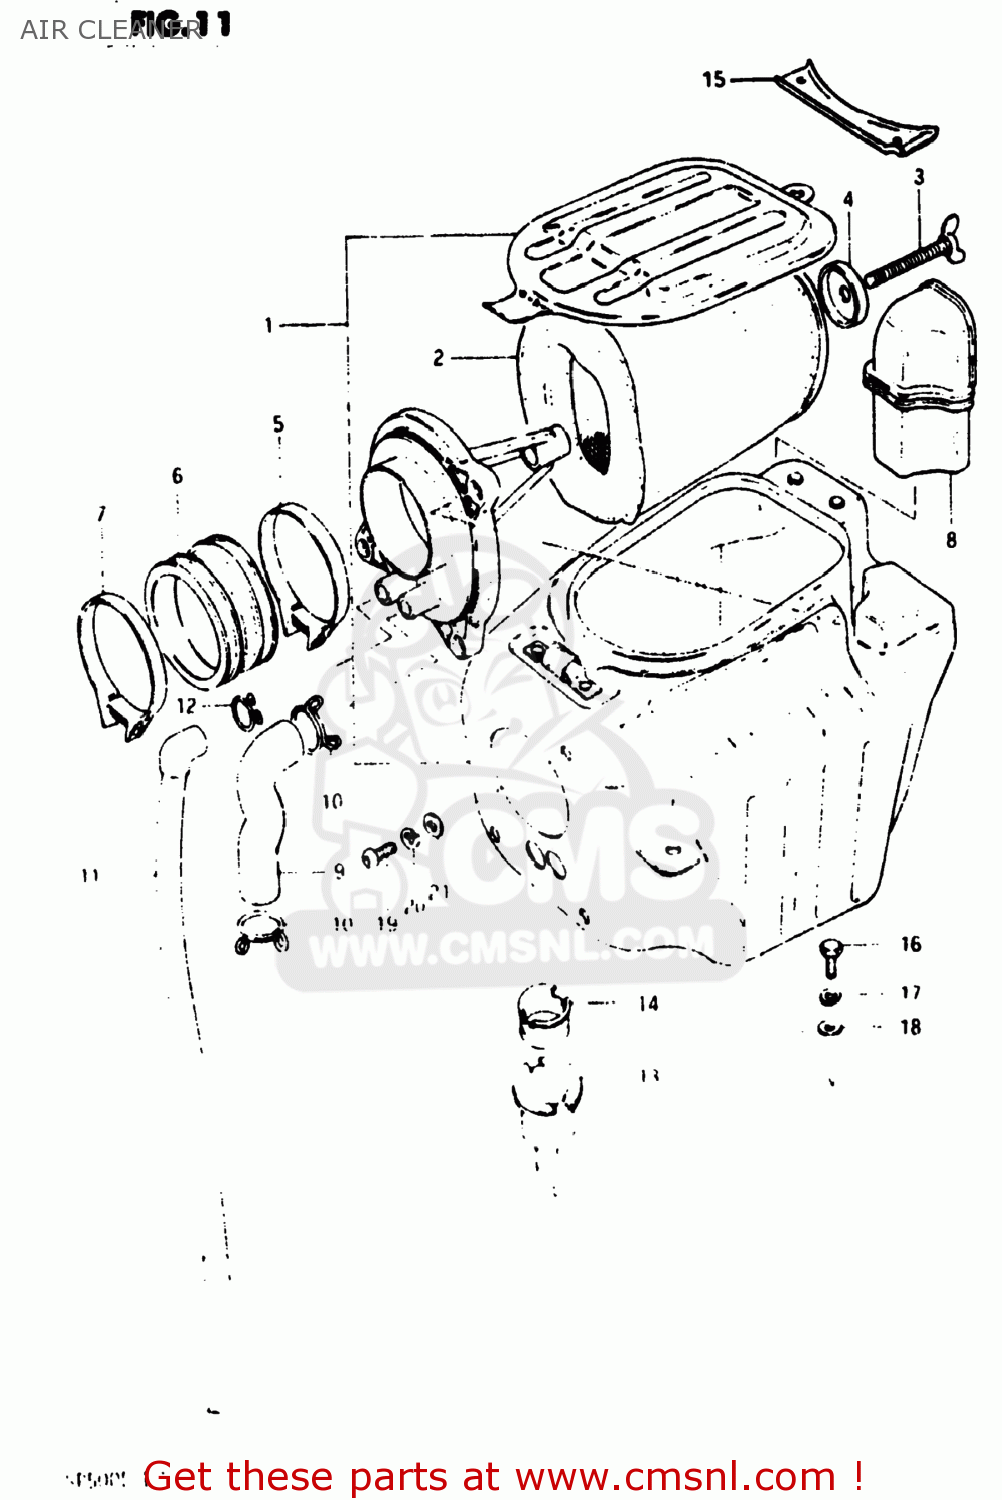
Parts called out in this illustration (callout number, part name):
1	CLEANER ASSEMBLY,AIR
2	FILTER
3	WING BOLT,AIR CLEANER
4	HOLDER,FILTER
5	CLAMP
6	TUBE,OUTLET
7	CLAMP
8	TUBE,INLET
9	HOSE,INLET
10	TUBE,BREATHER
11	CLIP
12	DRAIN TUBE
13	CLIP
14	HOSE,AIR CLEANER DRAIN
15	STOPPER,DRAIN
16	BRACKET,AIR CLEANER
17	BOLT, UPPER
18	LOCK WASHER
19	WASHER
20	SCREW 6X12
21	LOCK WASHER
22	WASHER
